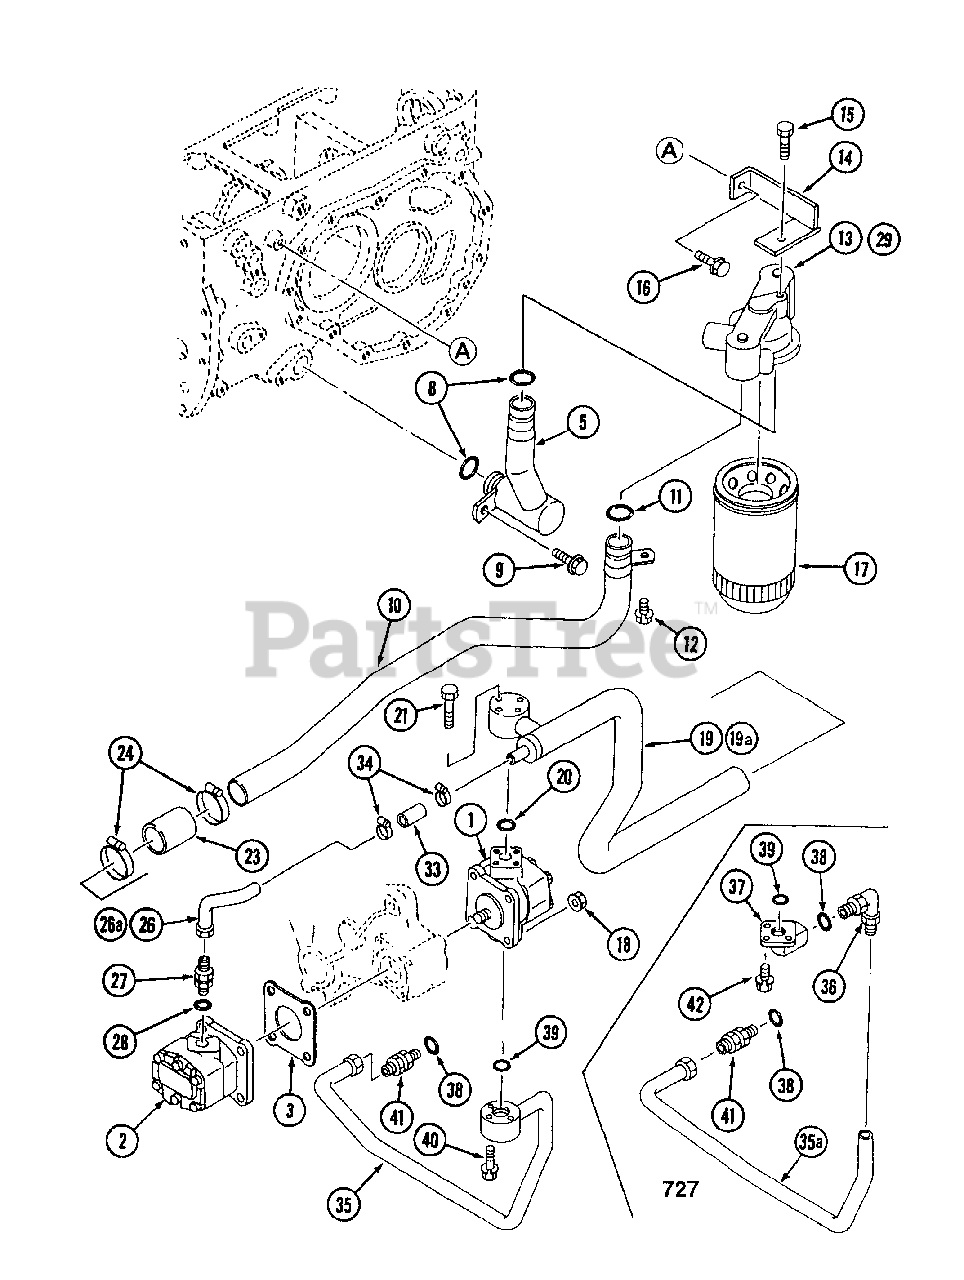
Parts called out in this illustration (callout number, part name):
1	Pump
2	Pump
5	Pipe, A Suction
10	Pipe, B Suction
19	Pipe, C Suction
19A	Pipe, D Suction
26	Pipe, E Ass'y.
26A	Pipe, F Suction Ass'y.
27	Body (Nipple)
29	Base, Filter
35	Pipe, A Pressure Ass'y.
35A	Pipe, B Pressure Ass'y.
36	Body (Elbow)
37	Joint
41	Body (Nipple)
42	Bolt
